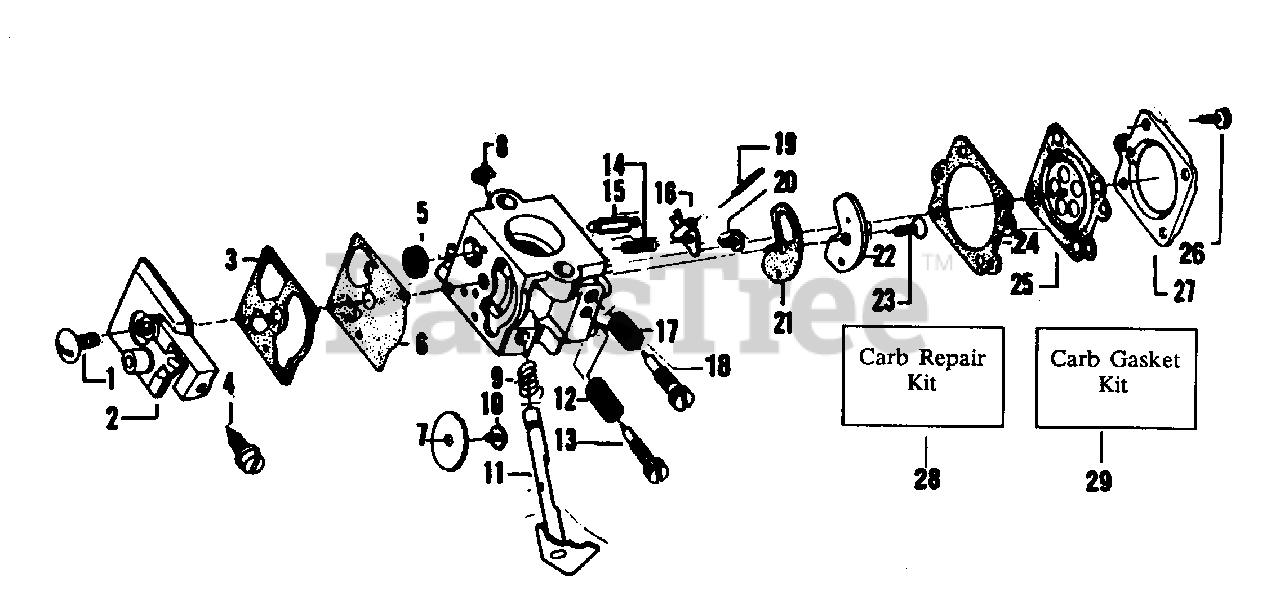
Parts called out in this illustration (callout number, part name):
1	Pump Cover Screw
2	Pump Cover Ass'y. (Inc.4)
3	Pump Gasket
4	Idle Adjustment Screw
5	Inlet Screen
6	Diaphragm Pump
7	Throttle Valve
8	Throttle Shaft Clip
9	Throttle Return Spring
10	Throttle Valve Screw
11	Shaft Ass'y. - Throttle
12	Idle Needle Spring
13	Idle Needle
14	Metering Lever Spring
15	Inlet Needle Valve
16	Metering Lever
17	Hi Speed Needle Spring
18	Hi Speed Needle
19	Metering Lever Pin
20	Metering Lever Pin Screw
21	Circuit Plate Gasket
22	Circuit Plate
23	Circuit Plate Screw
24	Metering Diaphragm Gasket
25	Metering Diaphragm Ass'y.
26	Metering Cover & Throttle Shaft Clip Ass'y. Screw
27	Metering Diaphragm Cover
28	Carb Kwik Repair Kit
29	Carb. Gasket/Diaphragm Kit
